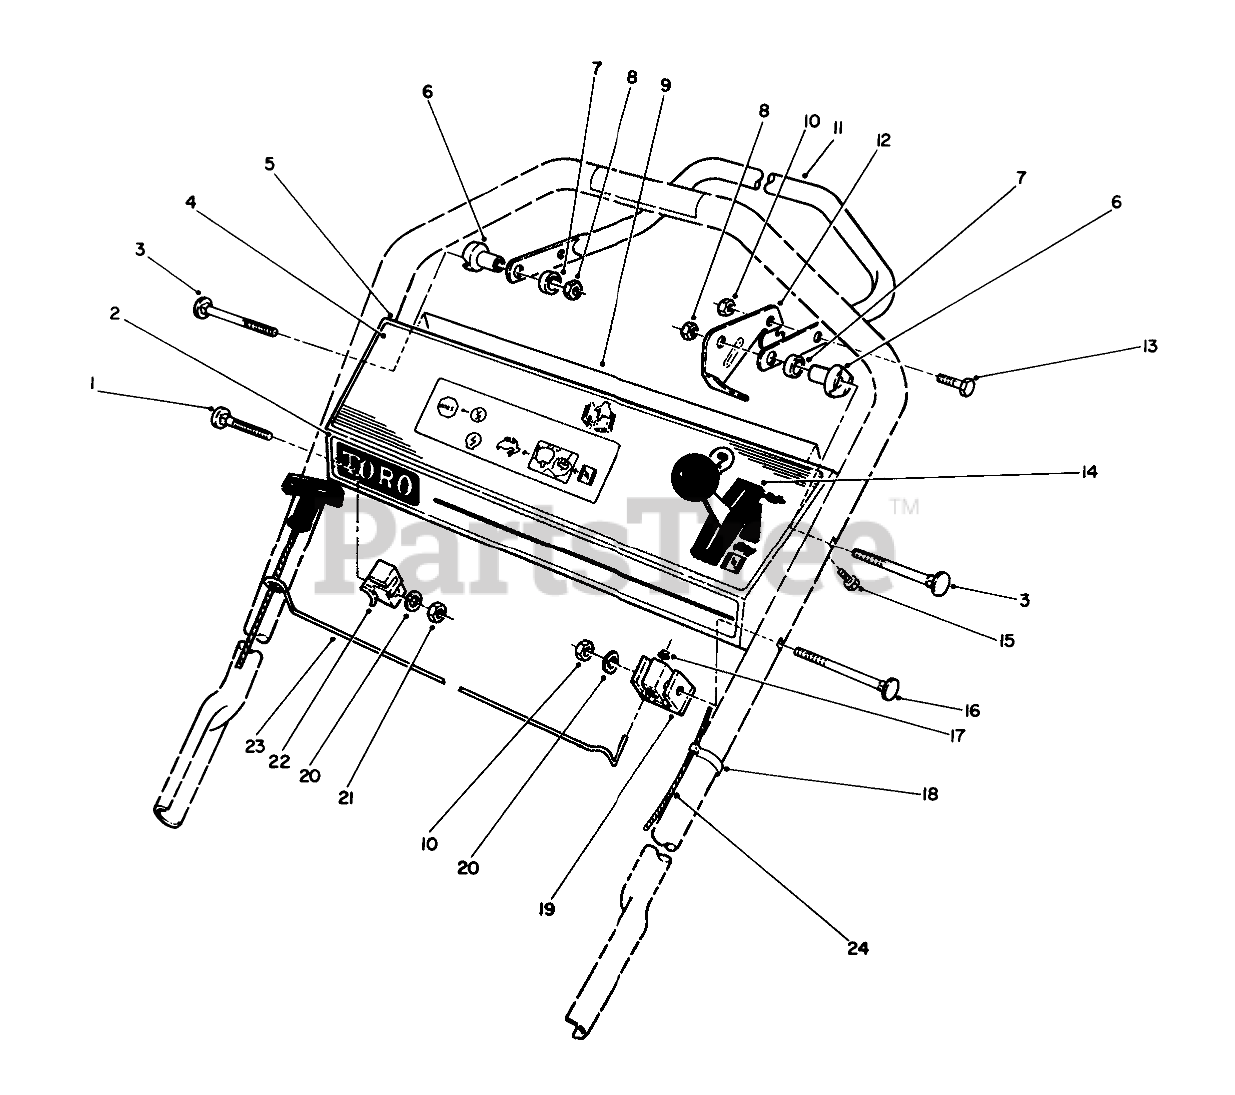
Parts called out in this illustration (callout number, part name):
1	SCREW-HANDLE
2	DECAL - TORO PANEL
3	Screw-Handle
4	Decal-Instruction
5	Control Panel
6	SPACER-SUPPORT
7	SPACER-NYLON
8	NUT-LOCK, NI
9	DECAL - PANEL, REAR
10	NUT-LOCK, NI
11	Bar-Control
13	SCREW-HH
14	Throttle Control (Bend Type 1) (Sheath Lg. 47 5/8" (Wire Lg. 2-3/84")
15	SCREW-HWHTF
16	HANDLE SCREW
17	216 Washer
18	BOWDEN CLIP
19	SUPPORT-CABLE
20	WASHER-FLAT
21	NUT-HEX
22	ROD CATCH
23	ROPE ROD PLATED
24	BRAKE CABLE
